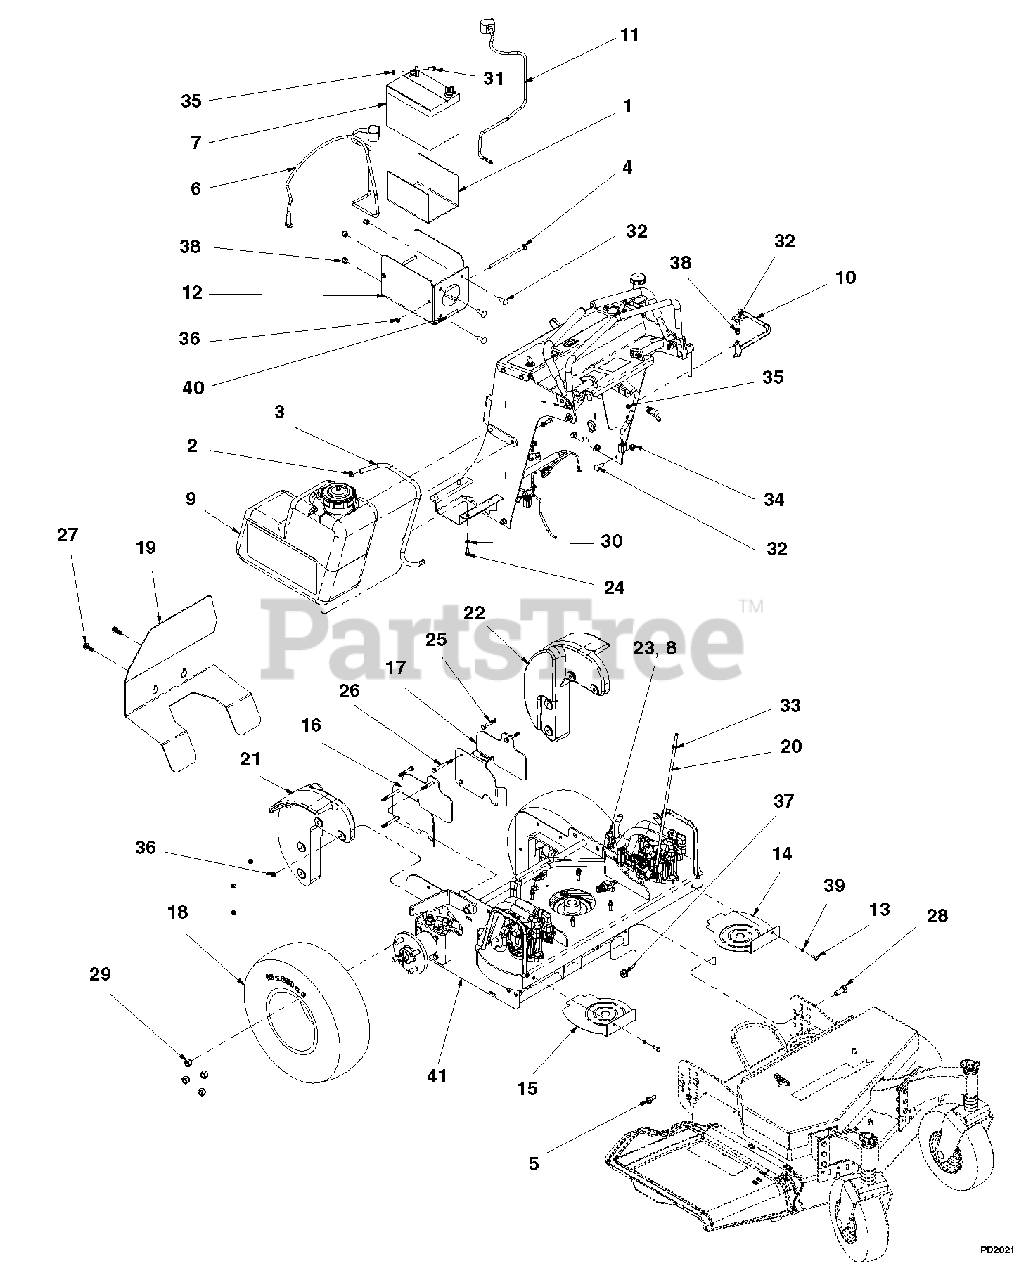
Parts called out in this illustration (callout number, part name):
1	Pad, Battery Insulator
2	Clamp, Hose (Red) #
3	Hose, 1/4" Id Low Perm Fuel 50
4	Cap Screw, 5/16" x 6"
5	Bolt, .50 x 1.06 x .375-16 Sld 5 Y
6	Cable, Battery Starter - 48"
7	Battery, 12V-U1-CCA 270 min
8	Pin, Clevis Spg 3/8" Yoke Spec Y
9	Tank, Fuel
10	Weldment, Reservior Guard
11	Cable, Battery - 25" Ground
12	Console Battery Bracket, w/Decal
13	Bolt, .25-20 x .750 Hex 5 Y
14	Shield, LH Pump
15	Shield, RH Pump
16	Shield, RH Motor
17	Shield, LH Motor
18	Assembly, Tire/Wheel 18/6.5 x 8 Slvr
19	Shield, Engine
20	Rod, Control 5/16 x 22.75 Y
21	RH Cast Weight Machined
22	LH Cast Weight Machined
23	Clevis, .38-24 Adjustment
24	Bolt, Hex .25-20 x .75 Grade 5
25	Bolt, Hex .31-18 x .75 Grade 5
26	Bolt, .312-18 x 3.00 Hex 5 Y
27	Bolt, .38-16 x 1.00 Fgh 8 Y
28	Bolt, Hex .50-13 x 1.25 Grade 5
29	Nut, .50-20 Lug C
30	Washer, .313 Med Sprg Lock Y
31	Bolt, .25-20 x .625 Wsh Y
32	Bolt, Round Head Square Neck .38-16x1.00 G 5
33	Nut, Hex .312-24
34	Nut, Flange .375-16
35	Nut, Locking-Flange .250-20
36	Nut, Locking-Nylon .312-18
37	Nut, Spin Lock-Flange .50-13
38	Nut, Locking-Nylon .38-16
39	Washer, .313 Medium Spring Lock Y
40	Trim, Rubber Edge 2"
41	Power Unit 19 Narrow
